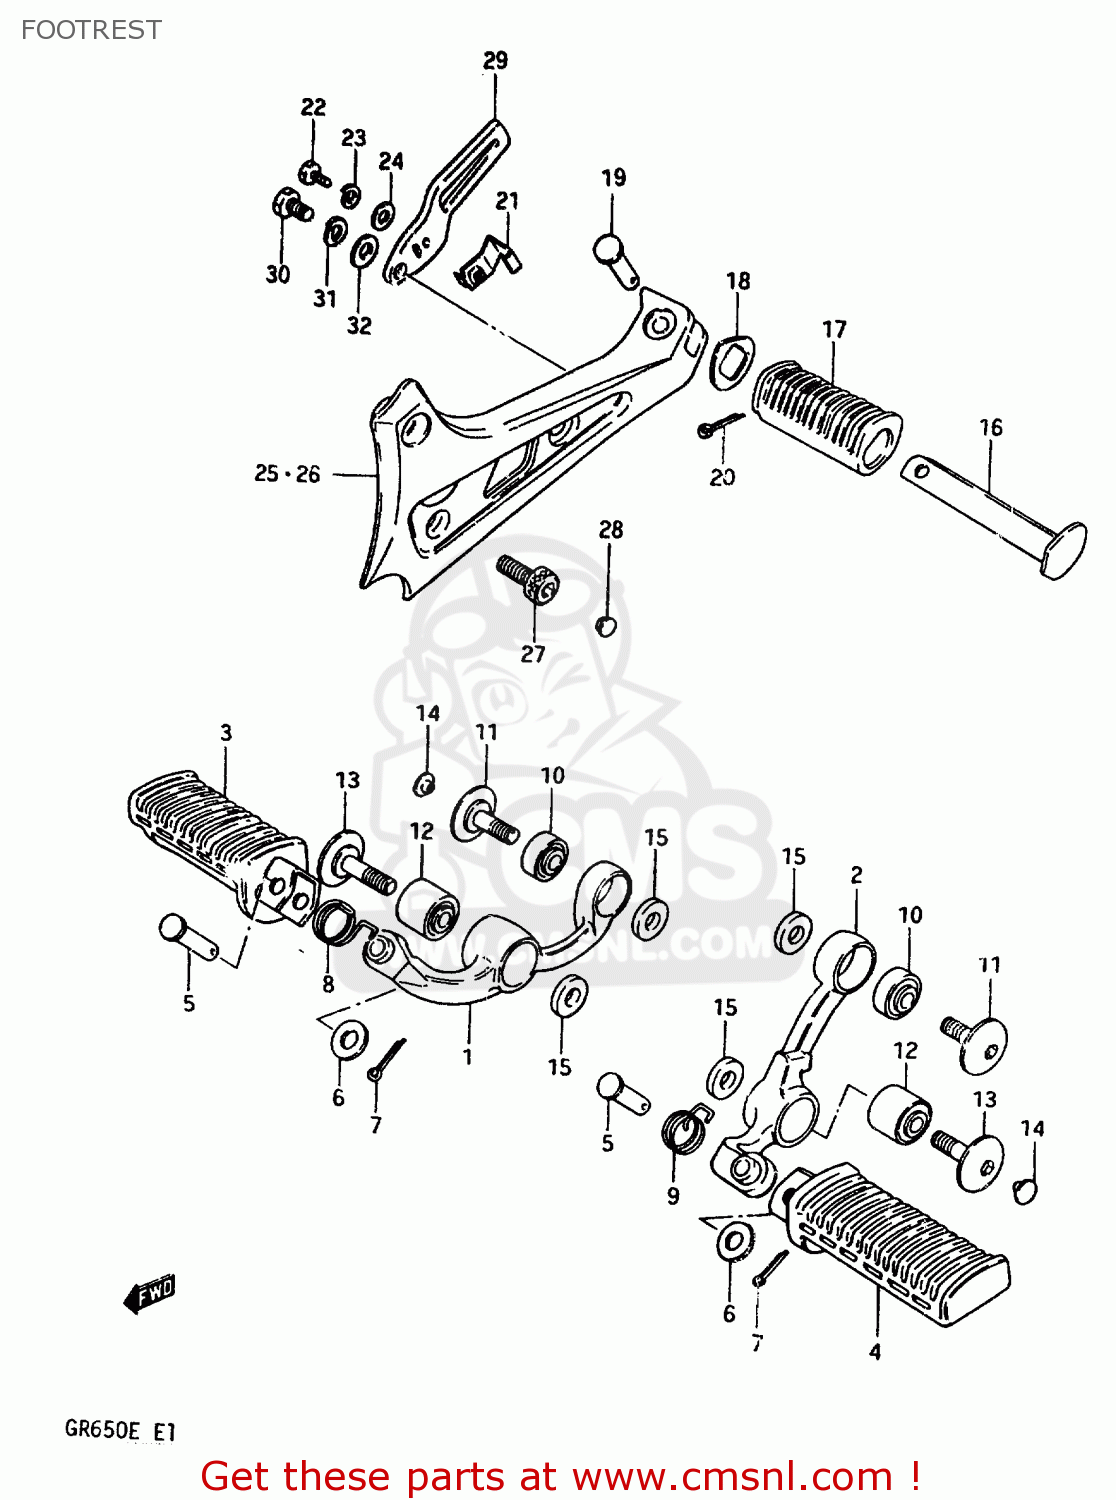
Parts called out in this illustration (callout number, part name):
1	BAR,FRONT FOOTREST,RIGHT
2	BAR,FRONT FOOTREST,LEFT
3	RUBBER,FOOTREST
4	FOOTREST
5	PIN
6	WASHER
7	PIN 20X20
8	SPRING
9	SPRING
10	BUSHING
11	BOLT 10X30
12	BUSHING
13	BOLT
14	CAP
15	WASHER (10.1X22X3.2)
16	BAR,REAR FOOTREST,LEFT
17	RUBBER,PILLION FOOTREST
18	WASHER,REAR FOOTREST RUBBER
19	PIN
20	PIN 20X20
21	COVER, PILLION FOOTREST
22	BOLT, UPPER
23	LOCK WASHER
24	WASHER
25	BRACKET,MUFFLER,RIGHT
26	BRACKET,MUFFLER,LEFT
27	BOLT
28	CAP
29	PLATE,FOOT GUIDE
30	BOLT
31	LOCK WASHER
32	WASHER
